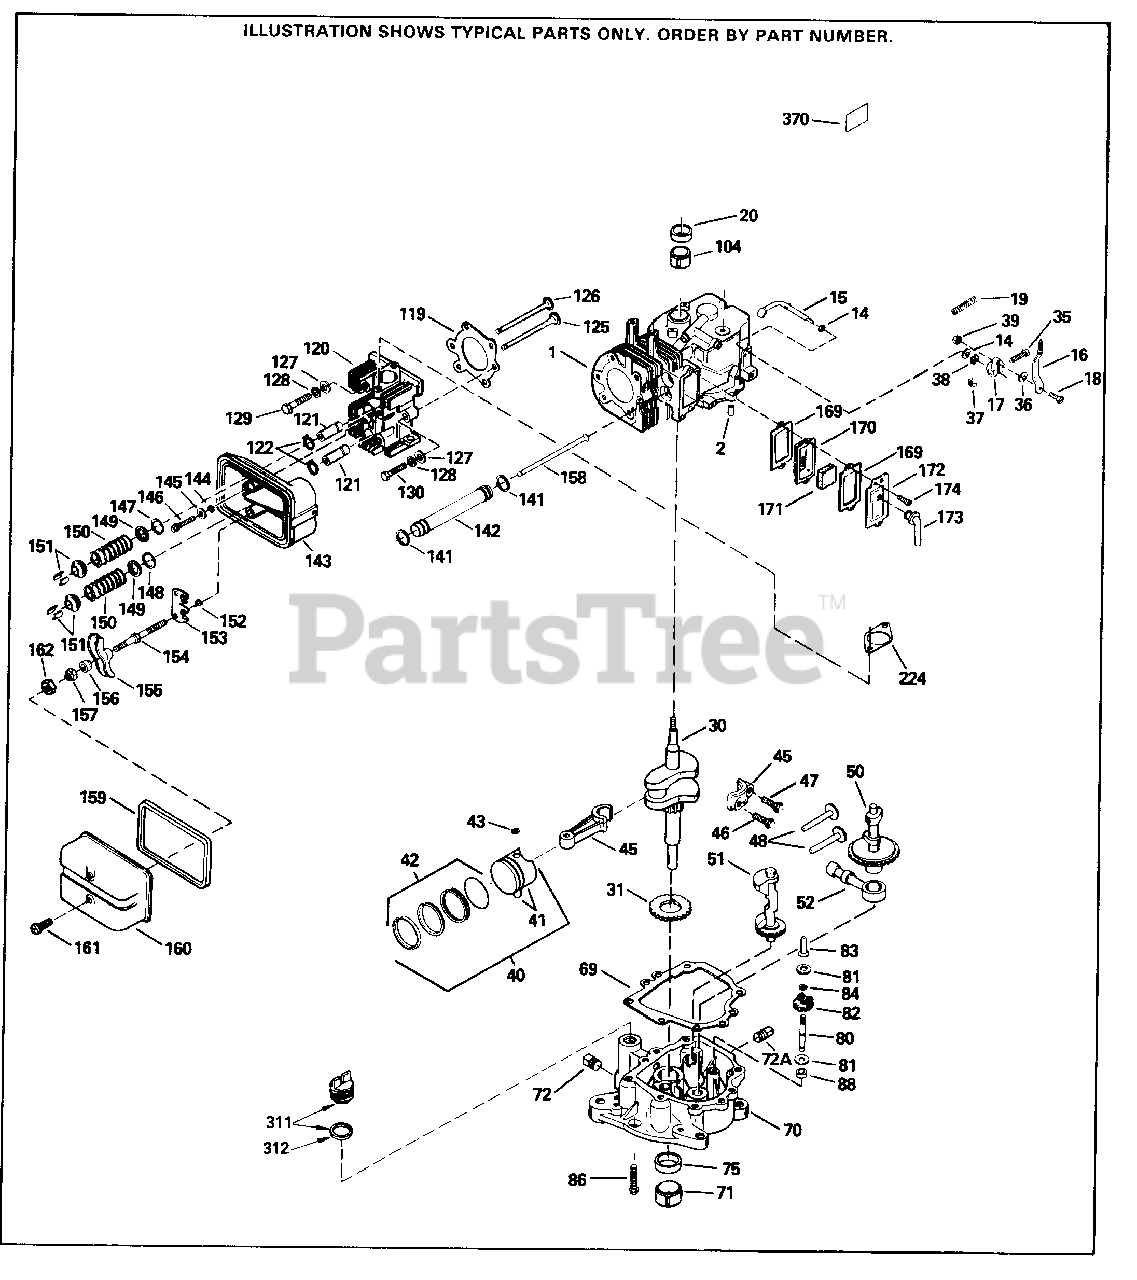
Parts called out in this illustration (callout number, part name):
1	"Cylinder (Incl. 2 & 20)
2	Dowel Pin
14	Flat Washer
15	Governor Rod
16	Governor Lever
17	Governor Lever Clamp
18	Screw, 8-32 x 5/16"
19	Extension Spring
20	Oil Seal
28	Lock Nut, 8-32
30	Crankshaft
31	Counterbalance Gear
35	Screw, 10-32 x 3/4"
36	Lock Washer #8
37	Lock Nut, 10-32
38	Retaining Ring
40	Piston, Pin & Ring Set (Std.)
40	Piston, Pin & Ring Set (.010" OS)
40	Piston, Pin & Ring Set (.020" OS)
41	Piston & Pin Ass'y. (Std.) (Incl. 43)
41	Piston & Pin Ass'y. (.010" OS) Incl. 43
41	Piston & Pin Ass'y. (.020" OS) Incl. 43
42	Ring Set (Std.) (3-5/16")
42	Ring Set (.010" OS)
42	Ring Set (.020" OS)
43	Piston Pin Retaining Ring
45	Connecting Rod Ass'y. (Incl. 46 & 47)
46	Connecting Rod Bolt
47	Connecting Rod Bolt
48	Valve Lifter
50	Camshaft (MCR)
51	Counterbalance Weight
52	Oil Pump Ass'y.
70	Mounting Flange (Incl. 71,72,75 & 80)
71	Crankshaft Bushing
72	Oil Drain Plug
72A	Pipe Plug
75	Oil Seal
80	Governor Shaft
81	WASHER
82	Governor Gear Assembly
83	Governor Spool
84	Retaining Ring
86	Screw, 1/4-20 x 1-3/16"
104	Crankshaft Bushing
119	Cylinder Head Gasket
119	Mounting Flange Gasket
120	Cylinder Head
121	Valve Guide Kit (Incl. 2 of 122)
122	Retaining Ring
125	Exhaust Valve (Std.)
125	Exhaust Valve (1/32" OS)
126	Intake Valve (Std.)
126	Intake Valve (1/32" OS)
128	Belleville Washer
129	Screw, 5/16-18 x 1-3/8"
130	Screw, 5/16-18 x 1-3/4"
141	"O" Ring
142	Push Rod Tube
143	Rocker Arm Housing
144	"O" Ring
146	Screw, 1/4-20 x 29/32"
148	"O" Ring
149	Valve Spring Cap
150	Valve Spring
151	Valve Spring Keeper
152	"O" Ring
153	Push Rod Guide
154	Rocker Arm Stud
155	Rocker Arm
156	Rocker Arm Bearing
157	Lock Nut (Incl. 162)
158	Push Rod
159	"O" Ring (Incl. 2 of 161)
160	Rocker Arm Housing
161	Screw, Torx T-20, 8-32 x 1/2"
162	Jam Nut
169	Valve Cover Gasket
170	Breather Body
171	Breather Element
172	Valve Cover
173	Breather Tube
174	Screw, 10-24 x 1/2"
224	Intake Pipe Gasket
311A	Oil Fill Plug (Incl. 312) also availa ble in Packaged Part #740079
370	Instruction Decal
